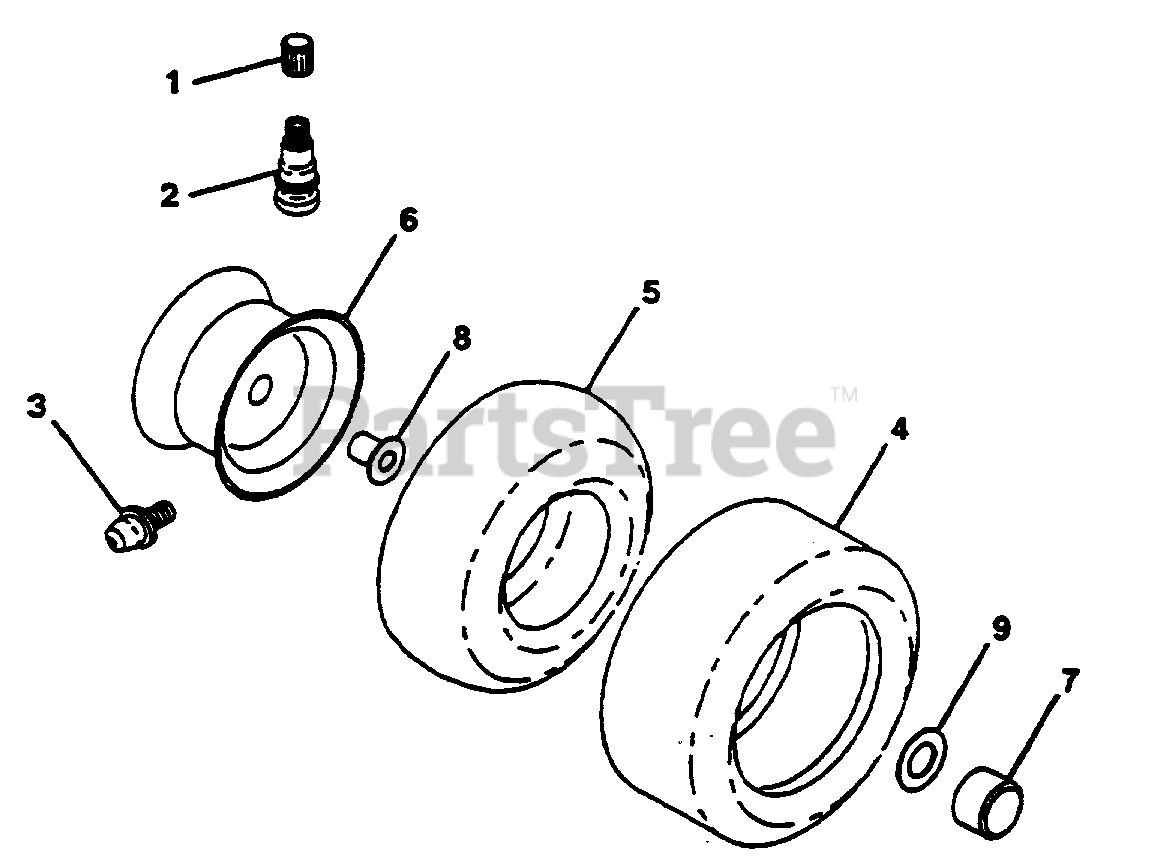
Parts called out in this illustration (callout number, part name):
3	Fitting, Grease
4	Tire, Front
5	Tube, Front Tire (Not Supplied)
7	Cover, Axle (Front and Rear)
8	Bearing, Flange (Front only)
9	Washer 25/32 x 1-5/8 x 16 Gauge
